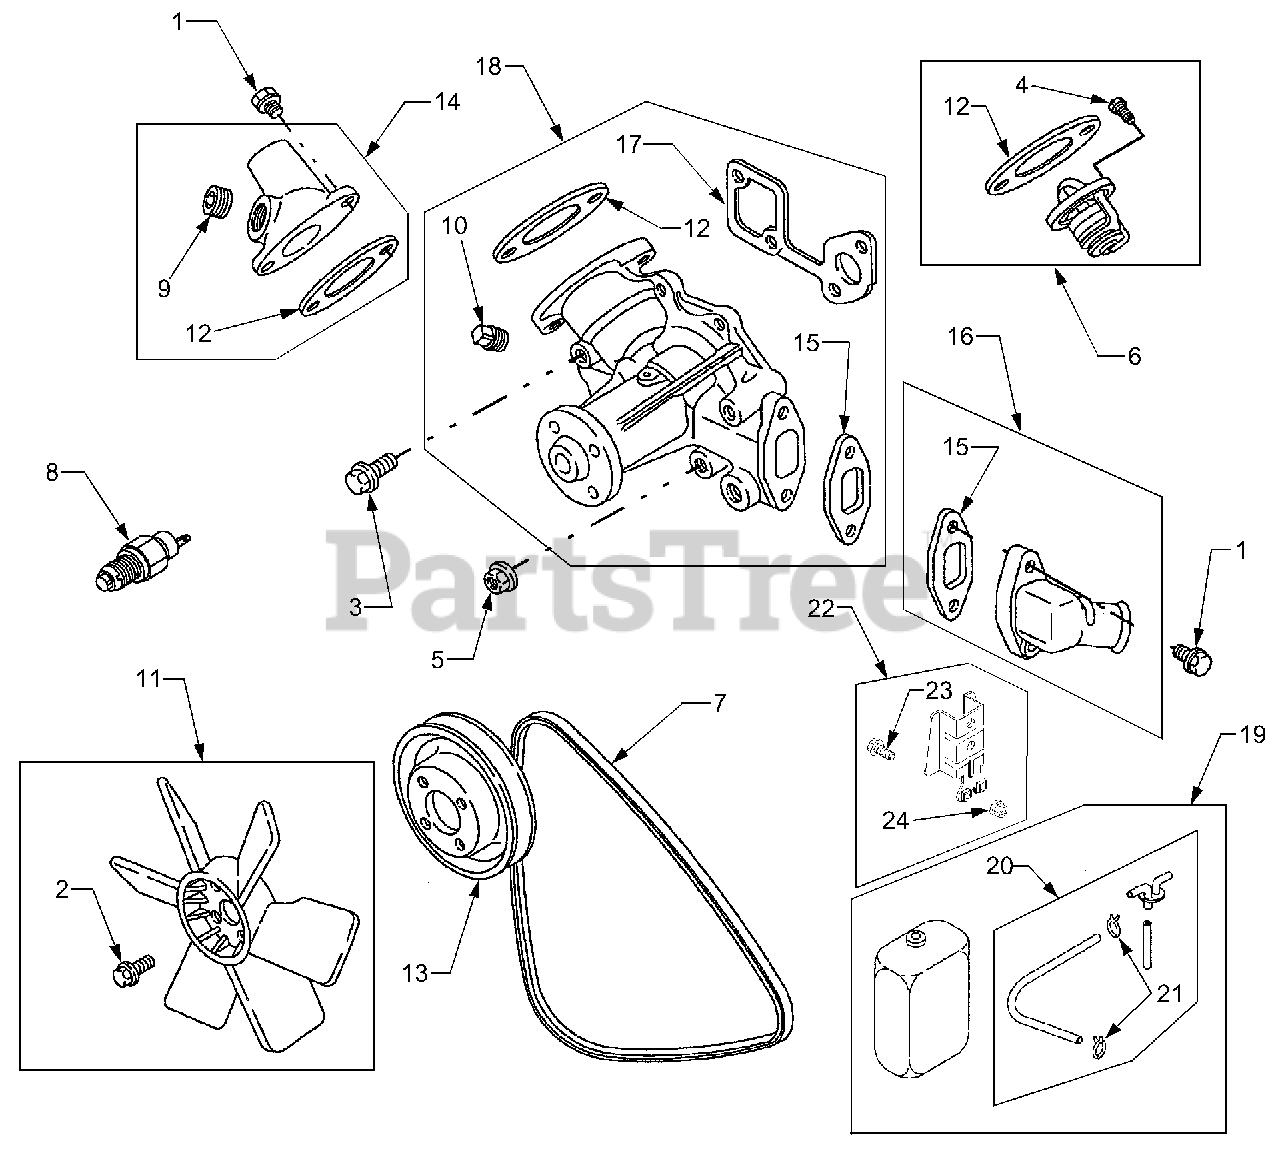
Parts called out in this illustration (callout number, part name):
1	Screw, Hex, 6mm
2	Screw, Hex,
3	Screw, Hex, 8mm
4	Screw, Metric
5	Nut, Hex Metric
6	Thermostat
7	Belt, V
8	Switch, Coolant Temperature
11	Fan, Radiator
12	Gasket, Outlet
13	Pulley, Pump
14	Housing, Outlet
15	Gasket, Inlet Housing
16	Housing, Inlet
17	Gasket, Water Pump
18	Pump, Water
19	Tank, Reserve
20	Cap, Reserve Tank
21	Clamp, Hose
22	Bracket, Reserve Tank Mtg
23	Screw, Mtg. Bracket
24	Nut, Mtg. Bracket
